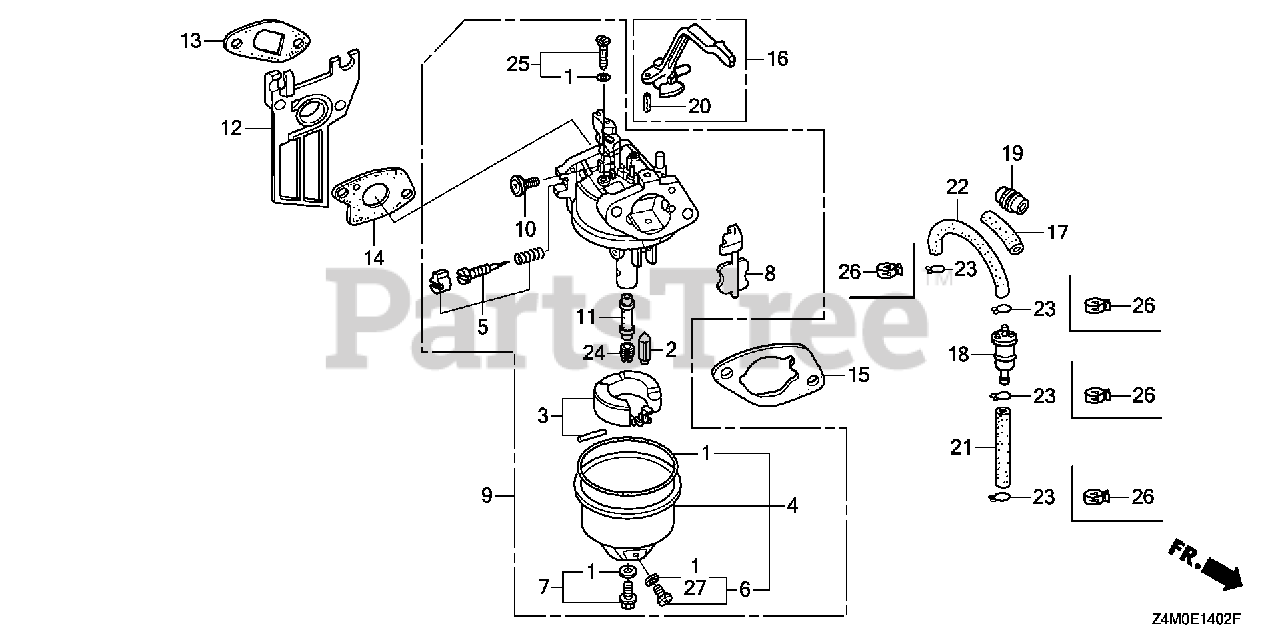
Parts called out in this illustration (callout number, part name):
1	GASKET SET
2	VALVE SET, FLOAT (SEAT NOT INCLUDED)
4	CHAMBER SET, FLOAT
5	SCREW SET, PILOT
6	SCREW SET, DRAIN
9	CARBURETOR ASSY. (BE67W B)
10	SCREW, THROTTLE STOP
11	NOZZLE, MAIN
12	INSULATOR, CARBURETOR
13	GASKET, INSULATOR
14	GASKET, CARBURETOR
15	GASKET, AIR CLEANER
16	LEVER, CHOKE
19	RUBBER, FUEL (9X15X20)
20	PIN, SPRING (2X12)
22	TUBE, FUEL (4.2X180) (FKM)
22	TUBE, FUEL (4.5X180) (FKM)
24	JET, MAIN (#72)
24	JET, MAIN (#75)
24	JET, MAIN (#70)
25	JET SET, PILOT (#35)
26	CLAMP, TUBE (D8)
